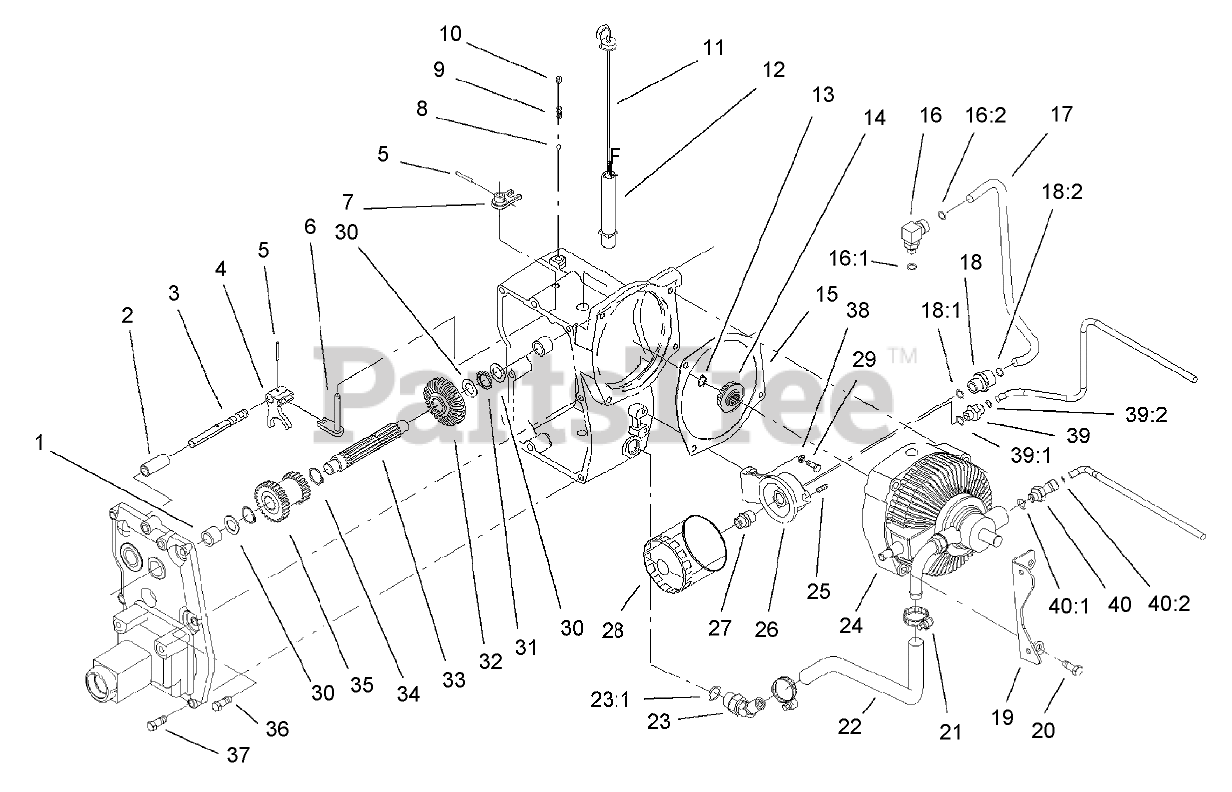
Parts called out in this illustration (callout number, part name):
1	BEARING-NEEDLE
2	TUBE-RAIL, SHIFTER
3	RAIL-SHIFT
4	FORK-HI / LO SHIFT
5	PIN-ROLL
6	ARM-SHIFTER
7	SHIFT-HI / LO
8	BALL-DETENT
9	SPRING-DETENT, SHIFT
10	SCREW-SET, HSH
11	DIPSTICK
12	TUBE-DIPSTICK
13	RING-SNAP, EXTERNAL
14	PINION-BEVEL
15	GASKET
16	FITTING -HYD, 90 DEGEE
16:1	O-RING
16:2	O-RING
17	TUBE-HYD
18	FITTING-STRAIGHT
18:1	O-RING
18:2	O-RING
19	PLATE-BRACKET, SUPPORT
20	SCREW-HH
21	CLAMP-DRIVE, WORM
22	HOSE-SUCTION
23	FITTING-HOSE
23:1	O-RING
24	TRANSMISSION-HYDRO
25	PLUG-PIPE
26	BASE-FILTER
27	FITTING
28	Filter-Oil
29	SCREW-HH
30	WASHER-THRUST
31	BEARING-THRUST
32	GEAR-BEVEL
33	SHAFT-INPUT
34	RING-RETAINING
35	GEAR-HI / LO
36	SCREW-HH
37	SCREW-HH
38	WASHER-LOCK
39	FITTING-STRAIGHT
39:1	O-RING
39:2	O-RING
40	FITTING-HYD, 45 DEGREE
40:1	O-RING
40:2	O-RING
